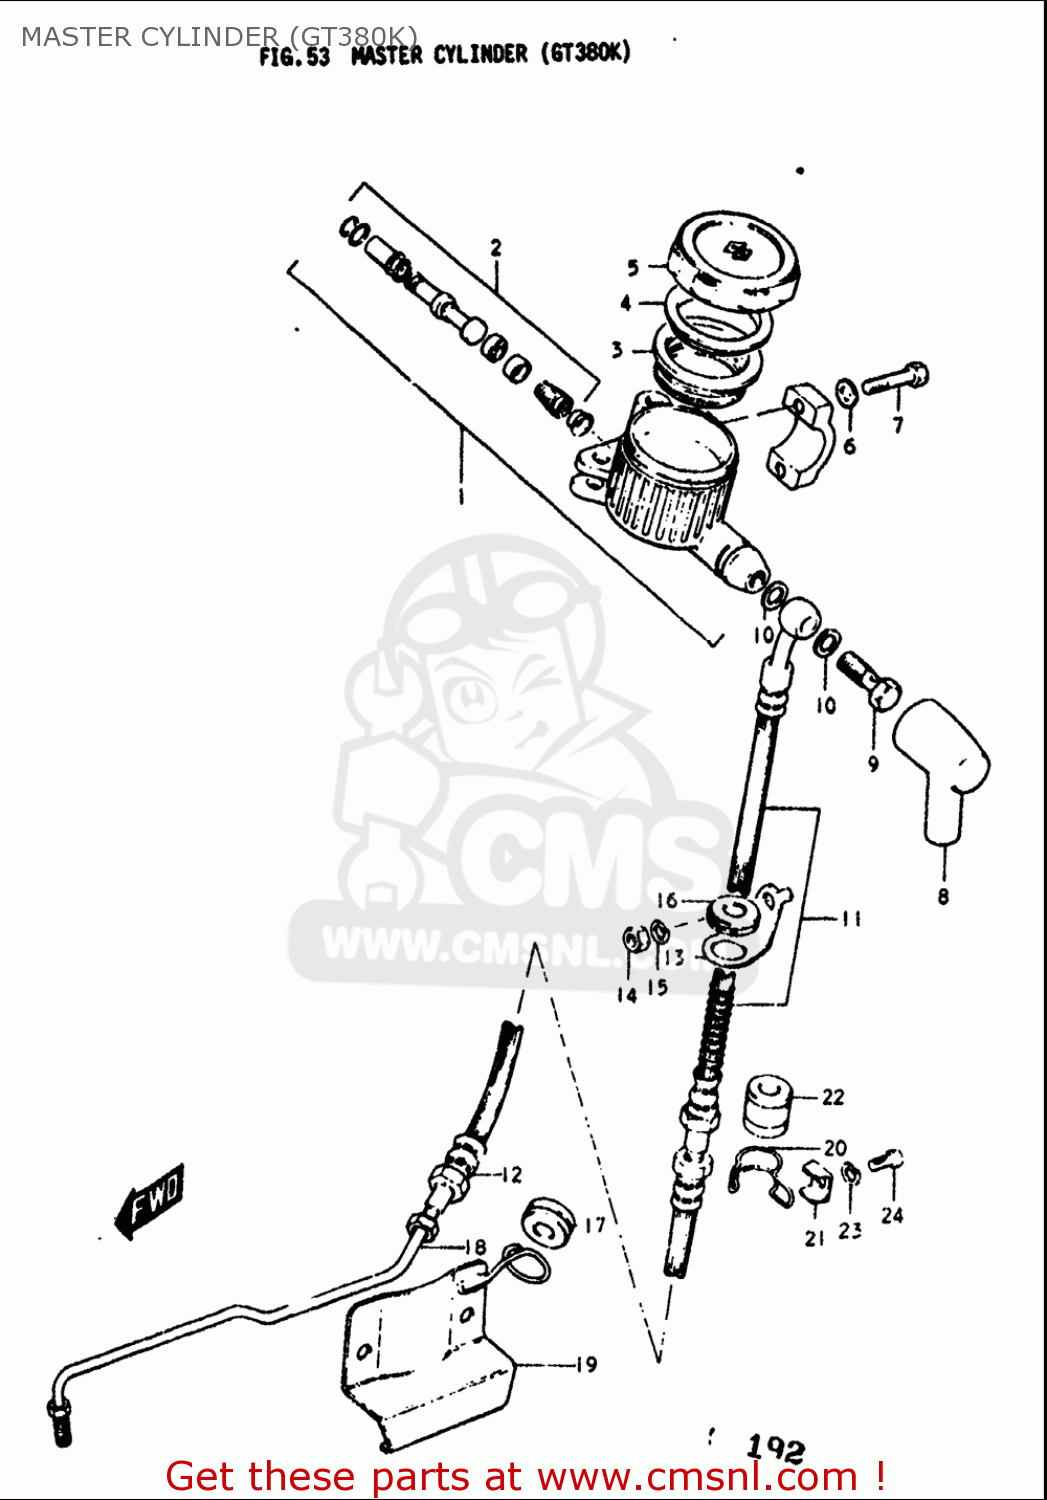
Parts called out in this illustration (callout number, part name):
2	PISTON & CUP SET
3	DIAPHRAGM
6	WASHER(6.5X20X1.6)
7	BOLT
8	BOOT,MASTER CYLINDER
9	BOLT UNION
10	WASHER(10X15X1.5)
14	NUT
15	WASHER,LOCK
16	GROMMET
23	WASHER,LOCK
24	SCREW(6X12)
